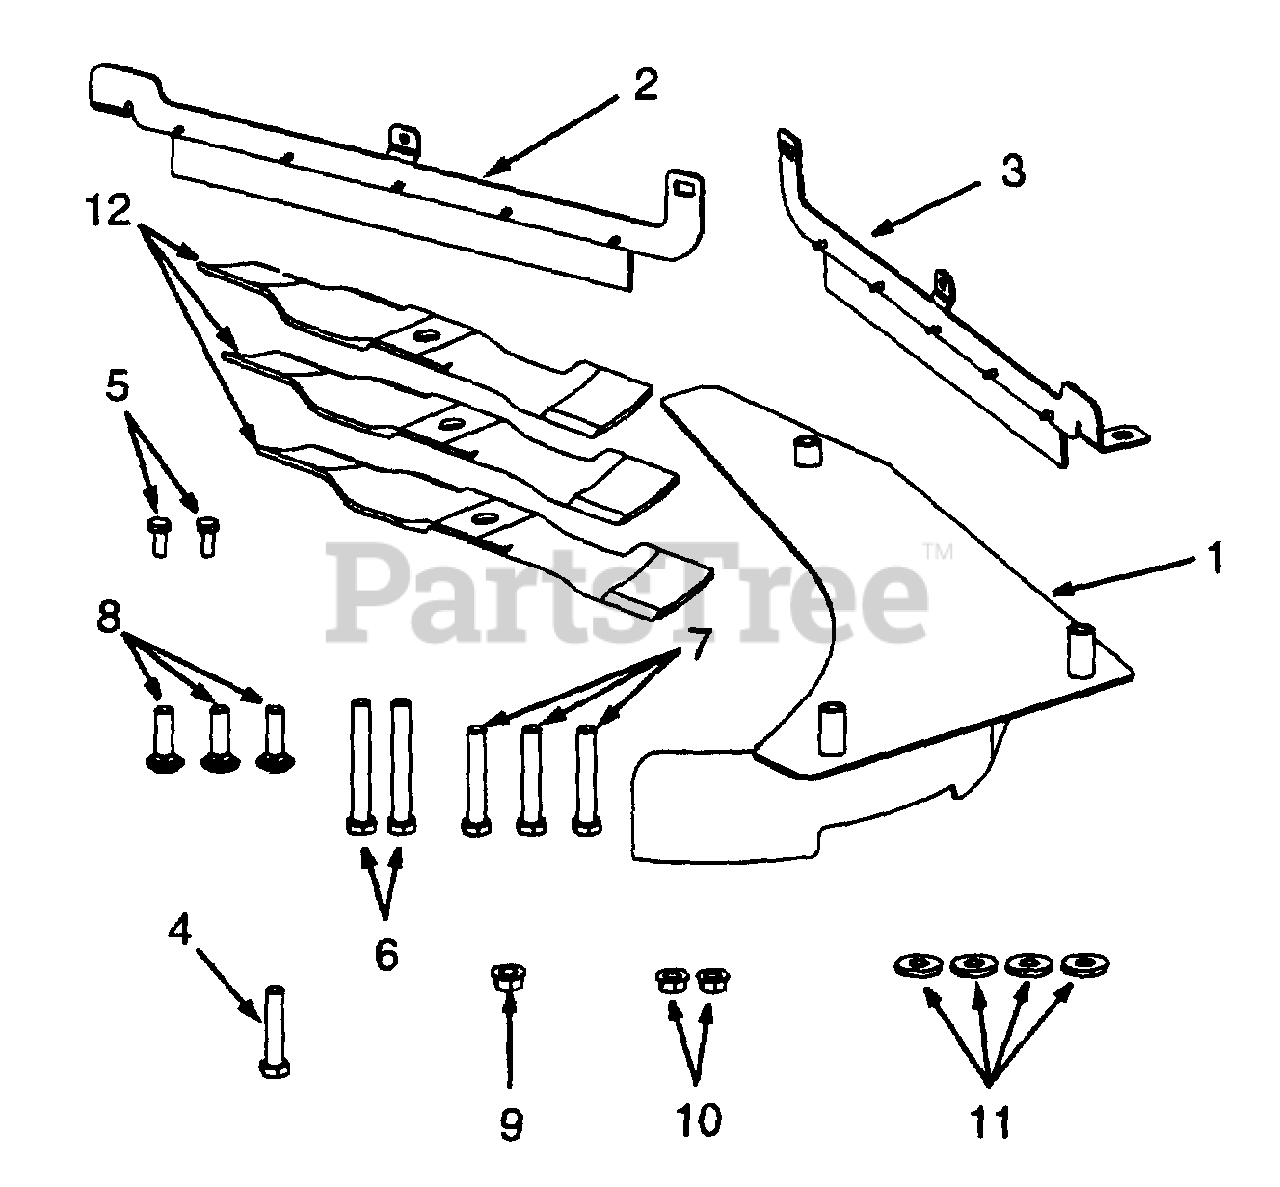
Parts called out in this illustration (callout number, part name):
3	Bracket Ass'y, Rubber Flap/Mtg RH
4	Screw, Hex Cap, 3/8-16 x 1.5 GR5
5	Screw, Hex Cap, 1/4-20 x .62 GR5
6	Screw, Hex Cap, 3/8-16 x 2.25 GR5
7	Screw, Hex Cap, 3/8-16 x 1.75
8	Bolt, Carriage, 3/8-16 x 1.0 GR5
9	Nut, Hex Flange Lock, 3/8-16
10	Nut, Hex Flange Lock, 1/4-20
11	Washer, Flat, .406 X 1.0 X .105
12	Blade, Mulching, 16.5 Lg
